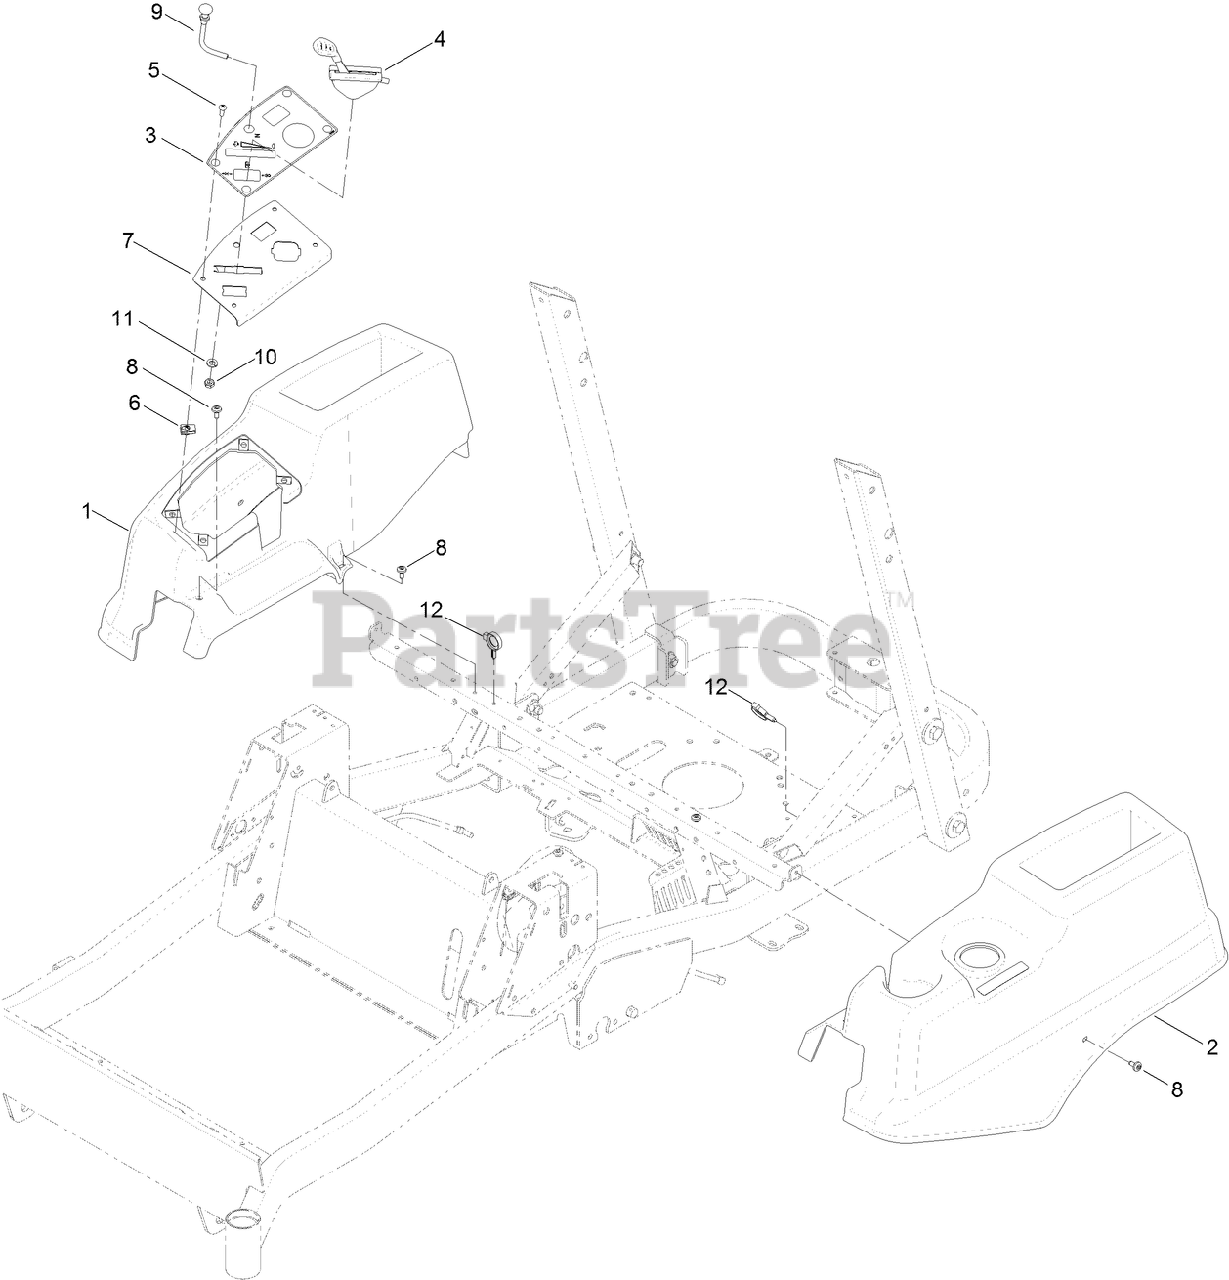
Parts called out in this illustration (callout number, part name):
1	POD-RH
2	POD-LH
3	DECAL-PANEL, CONTROL
4	CABLE-THROTTLE
5	SCREW-PRH
7	PANEL-CONTROL
8	SCREW-SHOULDER
9	CABLE-CHOKE
10	WASHER-LOCK
11	NUT-HJ
12	CLAMP-HOSE
